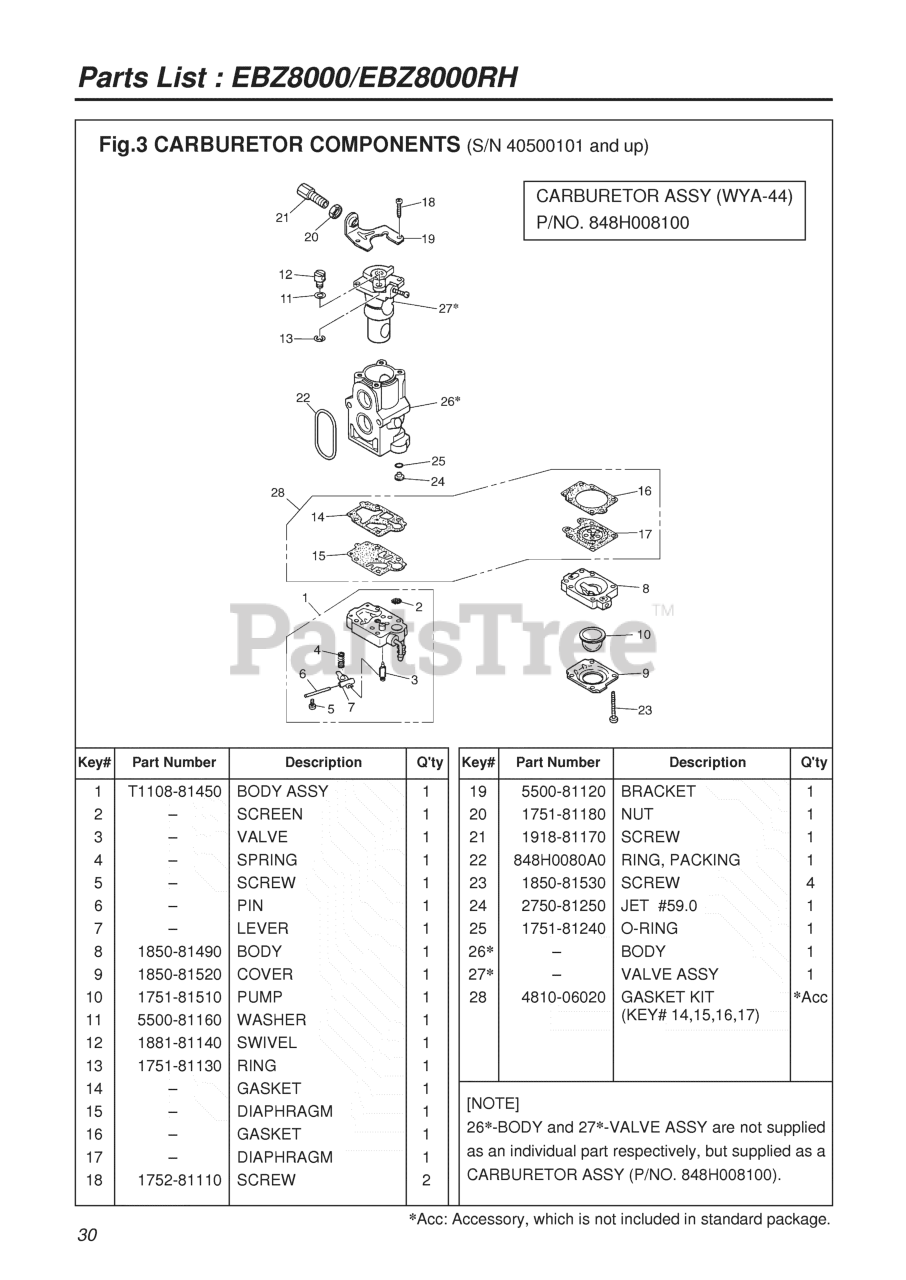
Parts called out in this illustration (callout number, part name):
1	BODY ASSY.
2	SCREEN
3	VALVE
5	SCREW
6	PIN
7	LEVER
8	BODY, PURGE
9	COVER, PUMP
10	PUMP, PRIMING
11	WASHER
12	SWIVEL
13	RING
14	GASKET
15	DIAPHRAGM
16	GASKET
17	DIAPHRAGM
18	SCREW
20	NUT, CABLE ADJUSTER
21	SCREW, CABLE ADJUSTER
22	RING, PACKING
23	SCREW
24	JET
25	RING, O
26	CARBURETOR-A (WYA-44)
27	CARBURETOR-A (WYA-44)
